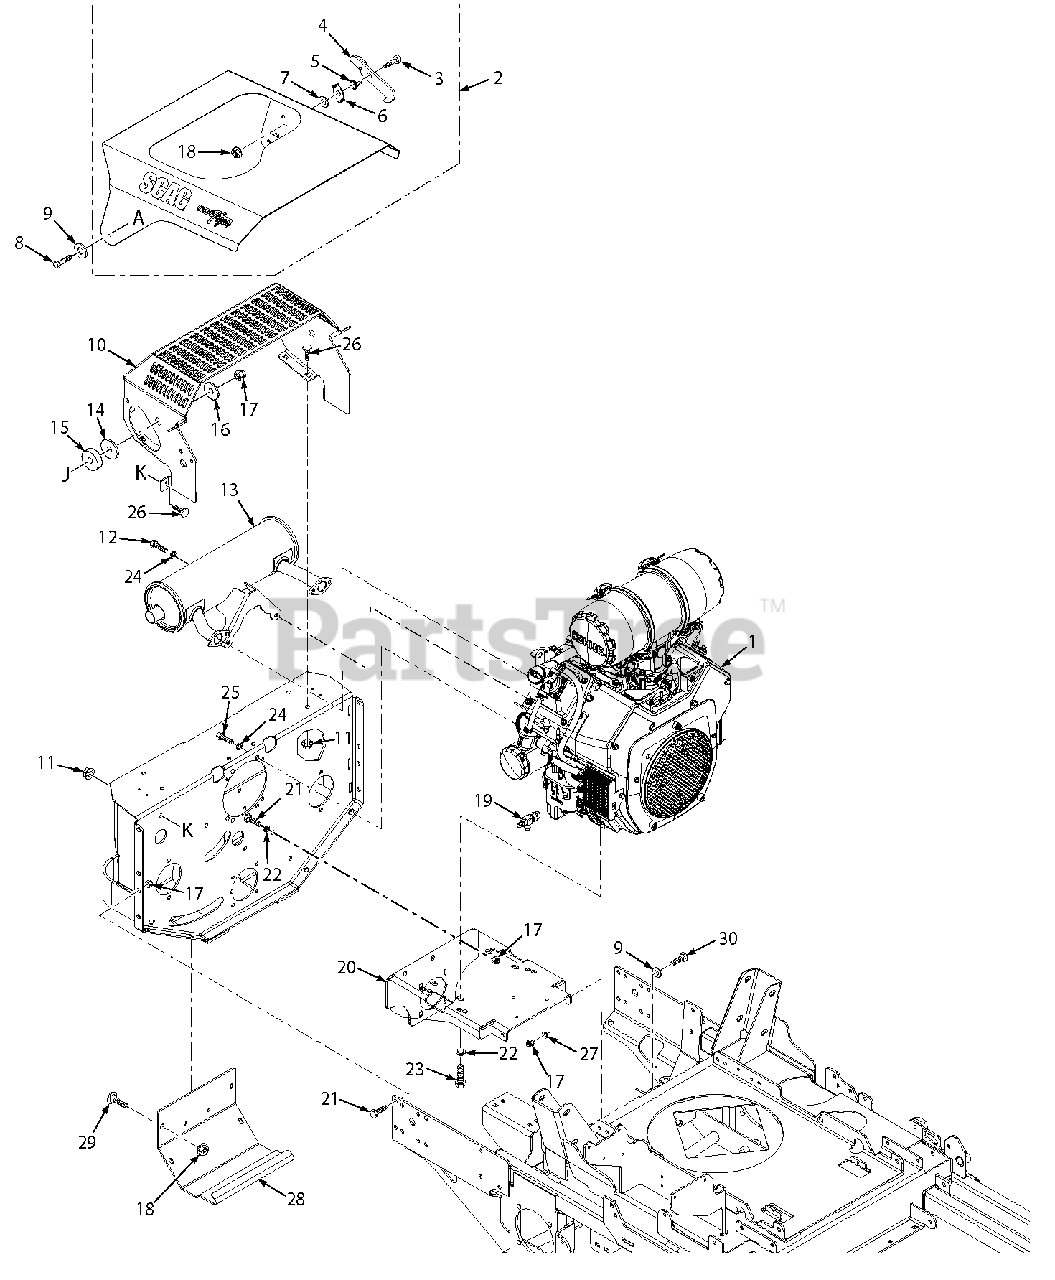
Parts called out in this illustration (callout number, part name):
1	Engine, 26EFI - Kohler
1	Engine, 35BV - Briggs & Stratton
1	Engine, 37BV-EFI - Briggs & Stratton
2	Hood Assy., STTII (EFI)
2	Hood Assy., STTII (35BV)
2	Hood Assy., STTII (37BV-EFI)
3	Bolt, Shoulder 3/8-1/2
4	Latch, Hood
5	Spring, Hood
6	Lock, Hood
7	Flatwasher, 3/8-.406 x .812 x .065
8	Bolt, Hex Head 3/8-16 x 1-3/4"
9	Flatwasher, 3/8-.391 x .938 x .105
10	Guard, Muffler
11	Nut, Flange Elastic Stop Nut, 5/16-18
12	Bolt, Hex Head 3/8-16 x 1"
13	Muffler, 26EFI - Kohler
13	Muffler, 35BV - Briggs & Stratton
13	Muffler, 37BV-EFI - Briggs & Stratton
14	Disc, Anti-Friction
15	Spacer, Hood
16	Flatwasher, 3/8-.406 x 1.50 x 7 Gauge
17	Nut, Elastic Stop 3/8-16
18	Nut, Serrated Flange 5/16-18
19	Oil Drain, 35BV & 37BV-EFI - Briggs & Stratton
20	Plate Weldment, Engine Mounting
21	Bolt, Hex Head 3/8-16 x 1"
22	Lockwasher, 3/8
22	Flatwasher, 5/16-.375 x .875 x .083 (35BV & 37BV-EFI)
23	Bolt, Hex Head 3/8-16 x 1-3/4" (Kohler EFI)
23	Bolt, Hex Head 5/16-18 x 2-1/2" (x3) (35BV & 37BV-EFI)
23	Bolt, Hex Head 5/16-18 x 2-1/2" (35BV & 37BV-EFI)
23	Nut, Serrated Flange 5/16-18 (35BV & 37BV-EFI)
24	Lockwasher, 3/8"
25	Bolt, Hex Head 3/16-1"
26	Bolt, Carriage 5/16-18 x 3/4"
27	Lockwasher, 3/8"
28	Cover, Rear
29	Bolt, Carriage 5/16-18 x 3/4"
30	Bolt, Hex Head 3/8-16 x 1-1/4"
